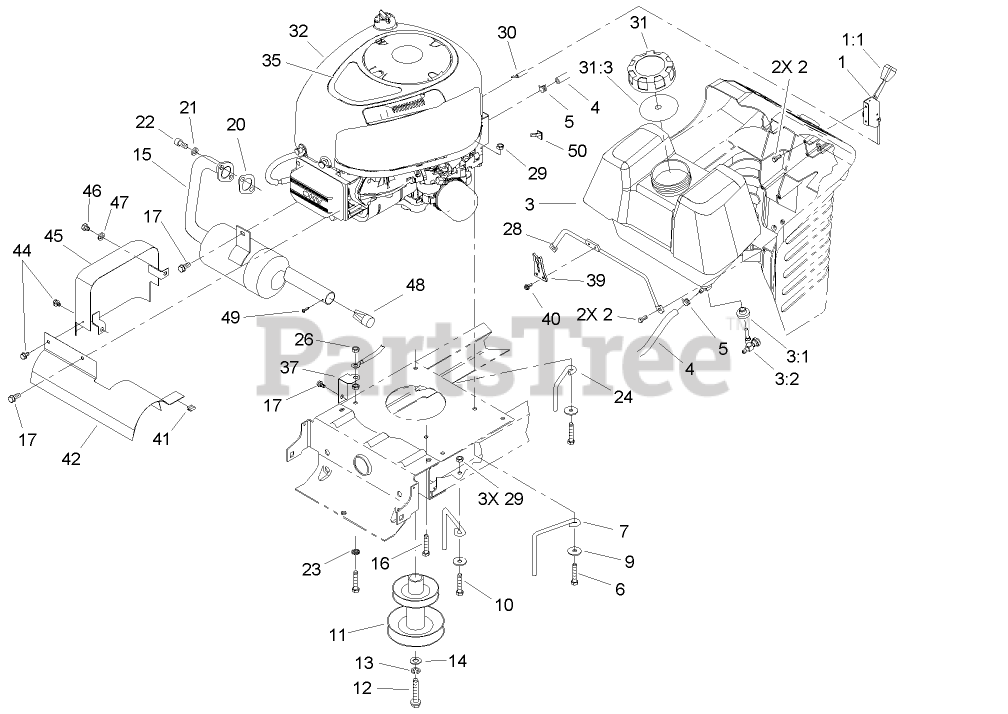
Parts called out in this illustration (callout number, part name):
1	THROTTLE CONTROL ASM
2	SCREW-SPECIAL
3	GAS TANK ASM
3:1	BUSHING
3:2	VALVE-FUEL
5	CLAMP-HOSE
6	SCREW-HH
7	GUIDE-BELT, ENGINE
9	WASHER-PIVOT
10	SCREW-HH
11	PULLEY-ENGINE
12	SCREW-HH
13	WASHER-LOCK
14	WASHER-FLAT
15	MUFFLER-EXHAUST
16	SCREW-HWH, TAPTITE
17	SCREW-HWH
20	GASKET-EXHAUST
21	WASHER-LOCK
22	SCREW-HSH
23	WASHER-LOCK
24	GUIDE-BELT, RH
26	NUT-KEPS
28	ROD-TANK, GAS
29	NUT-LOCK, NI
30	THROTTLE CABLE ASM
31	GAS CAP ASM
31:3	GASKET-CAP, GAS
32	Loose Parts Package
35	DECAL-ENGINE
37	BRACKET-GROUND
39	LATCH-HOOD
40	SCREW-HWH
41	CLIP-TINNERMAN
42	SHIELD-MUFFLER
44	SCREW-HWHTF
45	HEAT SHIELD ASM
46	SCREW-HH
47	WASHER-LOCK
48	SCREEN-SILENCER, EXHAUST
49	SCREW-THD FORM, HWH
50	REDUCER-THROTTLE, RPM
